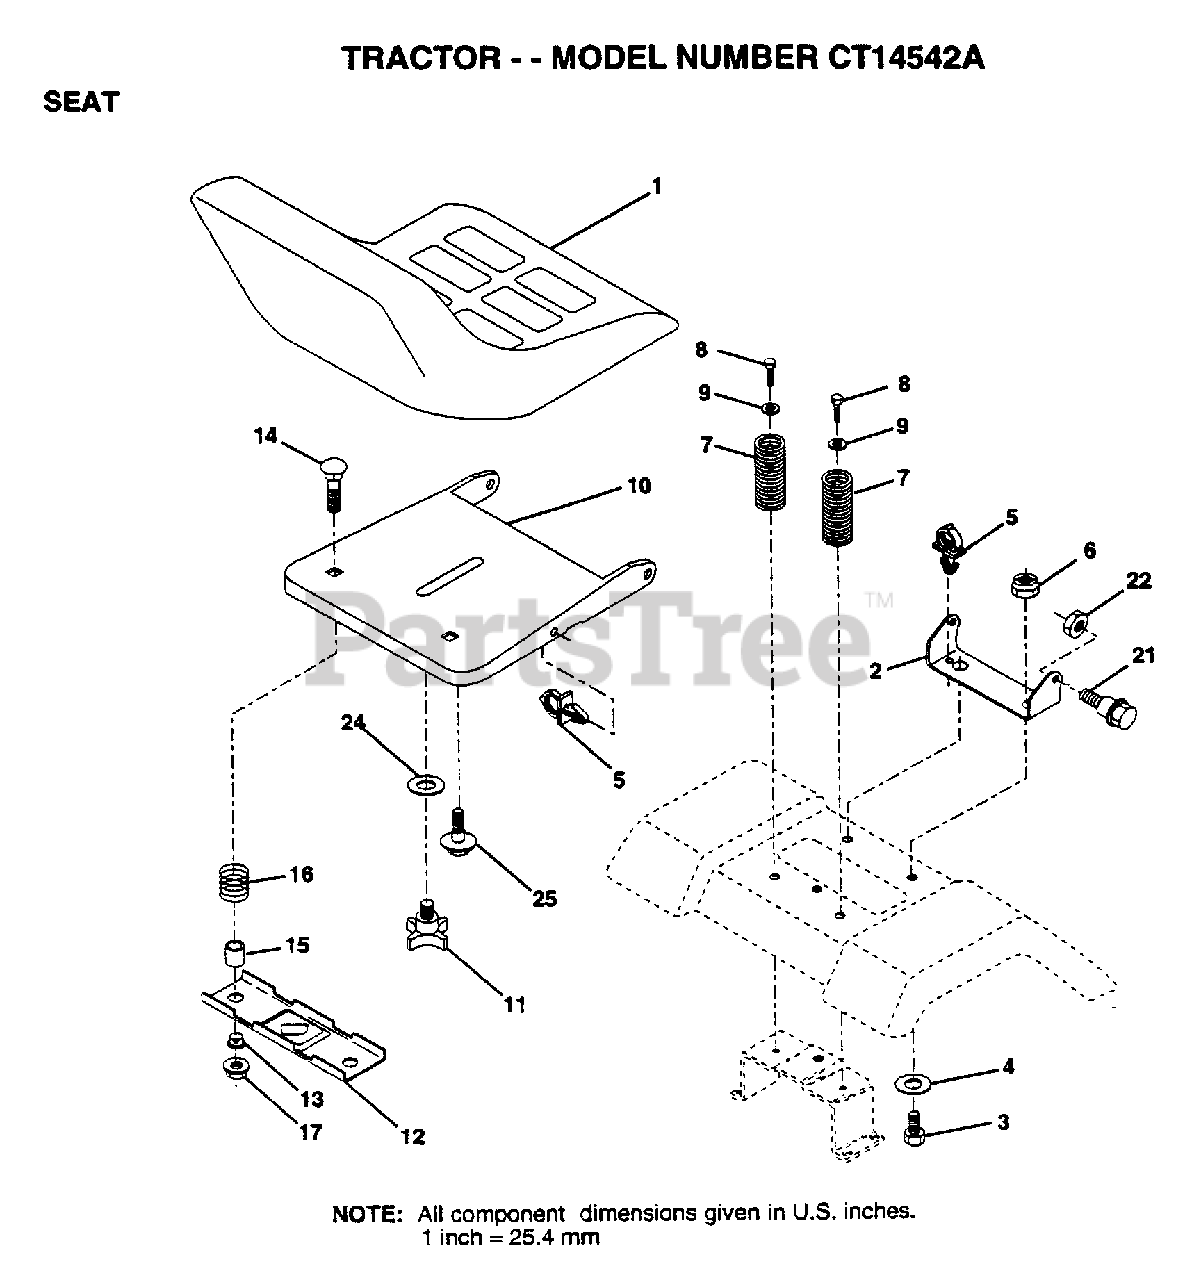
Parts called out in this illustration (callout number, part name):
2	BRACKET PVT SEAT
3	BOLT
4	WASHER PM
5	CLIP.PUSH-IN.HING
6	NUT
7	SPRING COMPRESSIO
8	SCREW GTV
9	WASHER
11	"KNOB 1/2"" YT"
12	BRKT SWITCH
13	BUSHING
15	SPACER SPLIT
16	SPRING COMPRESSED
21	BOLT.SHLD.5/16-18
24	WASHER
25	"BOLT,SHOULDER"
